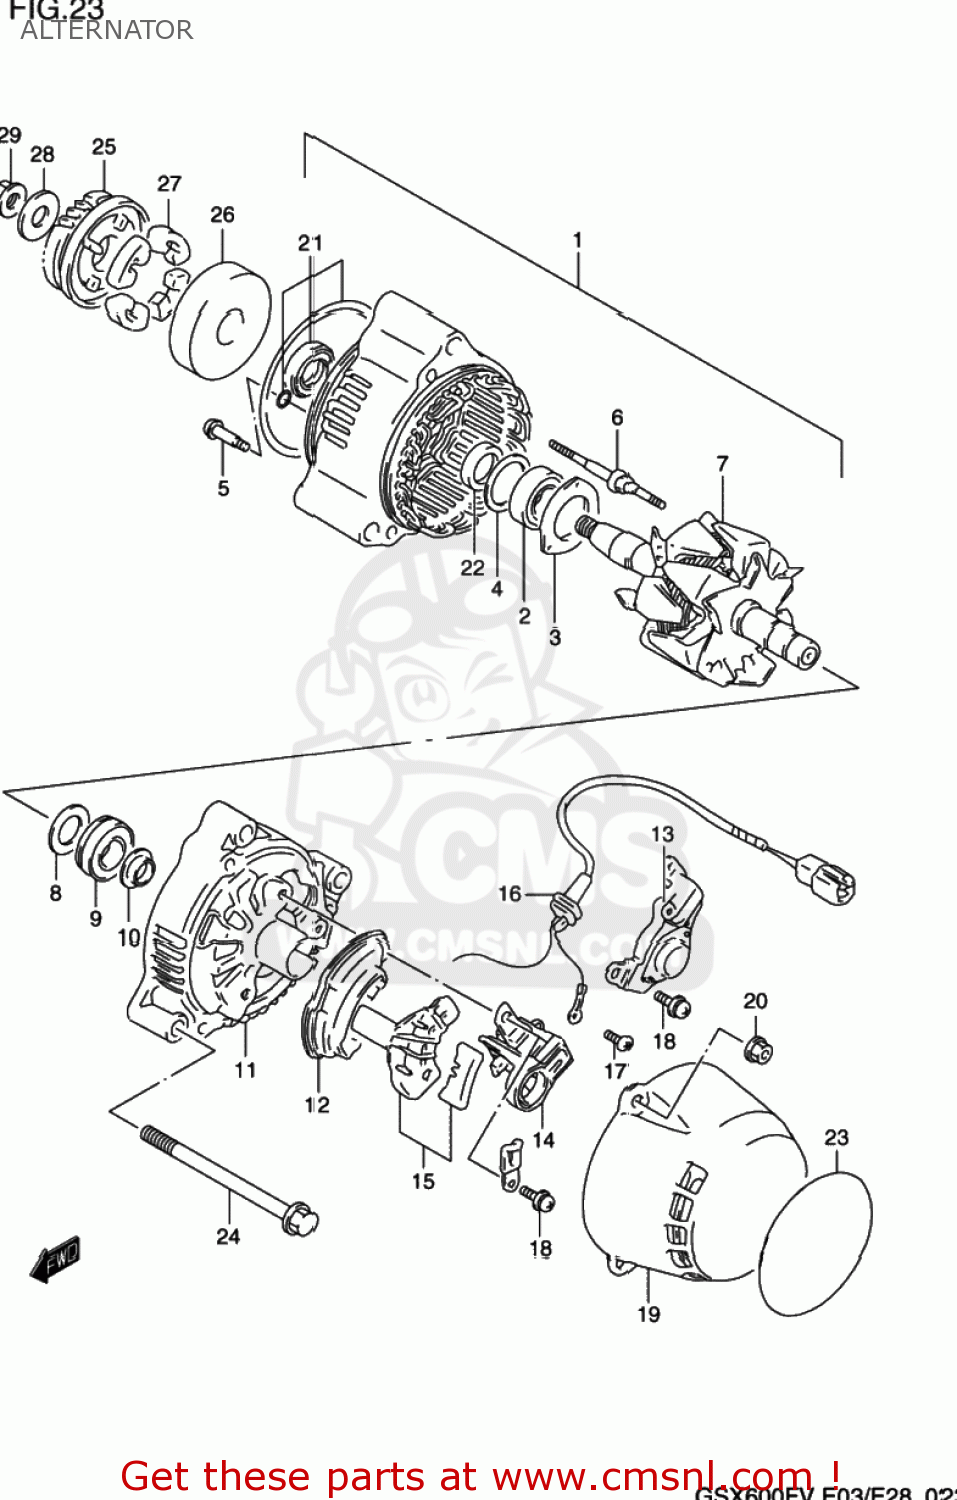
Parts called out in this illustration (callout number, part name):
1	ALTERNATOR ASSY
2	BEARING
3	RETAINER
4	COVER,BEARING
5	SCREW,BEARING RETAINER
6	STUD BOLT
7	ALTERNATOR ASSY
8	COVER,BEARING
9	BEARING
10	COVER(2)
11	FRAME,END
12	HOLDER,RECTIFIER
13	REGULATOR
14	HOLDER,BRUSH
15	COVER,RECTIFIER
16	WIRE,LEAD
17	SCREW 4X6
18	SCREW
19	COVER
20	NUT
21	SERVICE KIT(A)
22	SPACER
23	PLATE,ALTERNATOR ABSORBER
24	BOLT
25	GEAR,GENERATOR DRIVEN
26	HOUSING,GENERATOR GEAR
27	DAMPER,GENERATOR DRIVEN
28	WASHER
29	NUT
